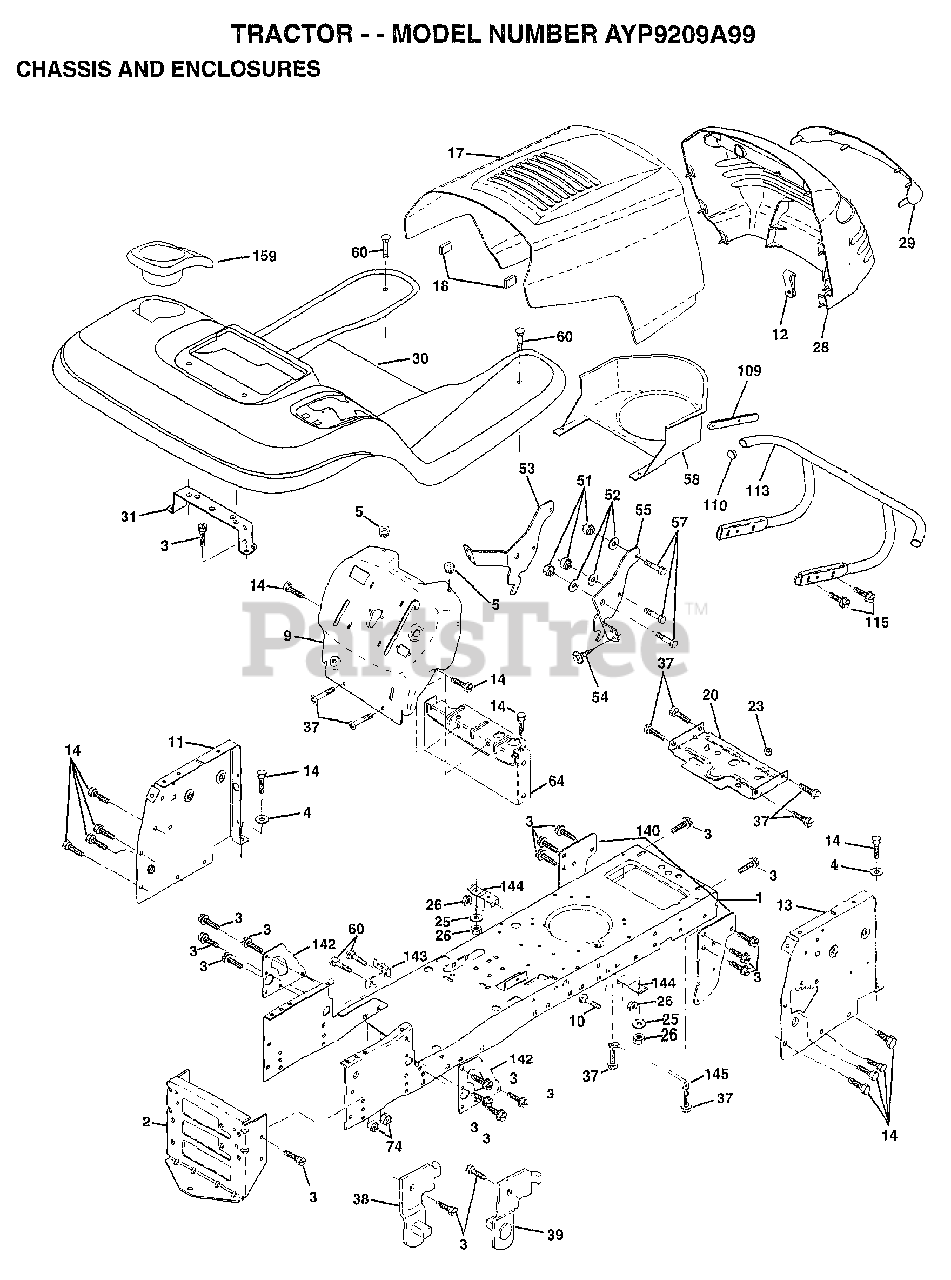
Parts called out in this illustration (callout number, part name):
1	CHASSIS.STLT.STAMPING
3	SCREW
4	WASHER
5	BUMPER-HOOD/DASH
9	DASH.PLM.SLKSCR.
11	"PANEL-DASH,LH"
12	CLIP.TINNERMAN
14	SCREW LT
17	HOOD.STEEL.PRVT
20	"PLATE-MTG,BATT/FU"
25	WASHER
26	NUT
28	GRILL
29	GRILLE.LENS
30	FENDER.FTREST.PNT.ST
31	BRACKET SUPT FEND
37	SCREW LT
38	BRACKET ASM LH
39	BRACKET ASM RH
51	NUT
52	WASHER
53	BRACKET.GRILLE.LH
54	SCREW.HEX.WS.HD
55	BRACKET.GRILLE.RH
58	AIR DUCT
60	BOLT
64	DASH-LOWER
109	BRACKET.EXT.BUMP.
110	PLUG.PLASTIC
113	BUMPER.ASM
115	SCREW
140	BRKT SUSPENSION
142	PLATE.REINFORCEMENT
143	"BRKT-S'BAR,CHASSI"
144	BRKT-FOOTREST
145	"ROD POVOT,CHASSIS"
159	CUPHOLDER.STLT.BLK
